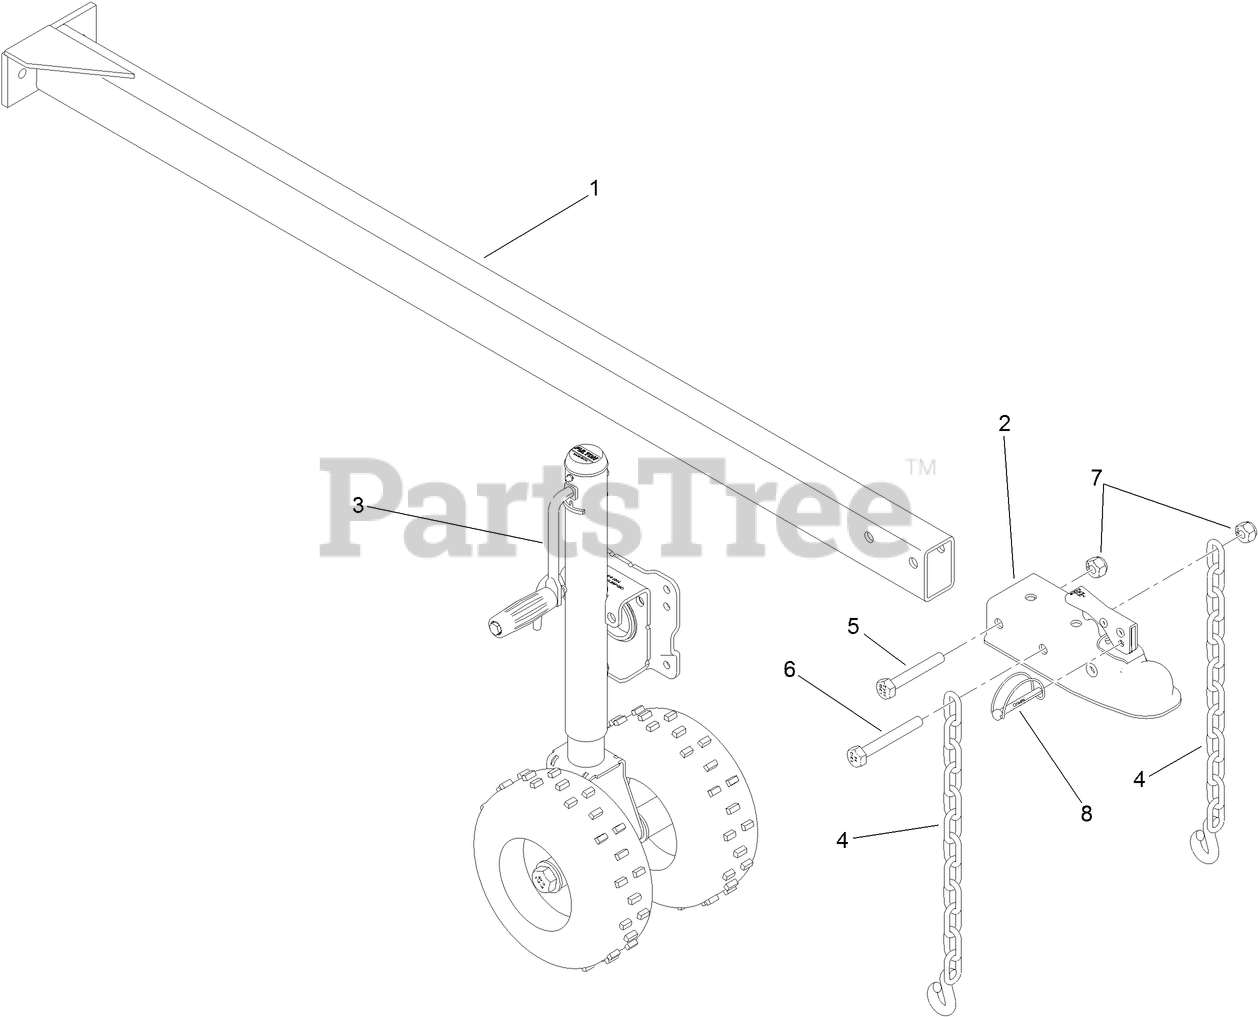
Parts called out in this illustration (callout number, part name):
1	TONGUE ASM
2	RECEIVER-HITCH, BALL
3	JACK ASM
4	CHAIN-SAFETY
5	SCREW-HH
6	SCREW-HH
7	NUT-LOCK
8	PIN-LOCKING
